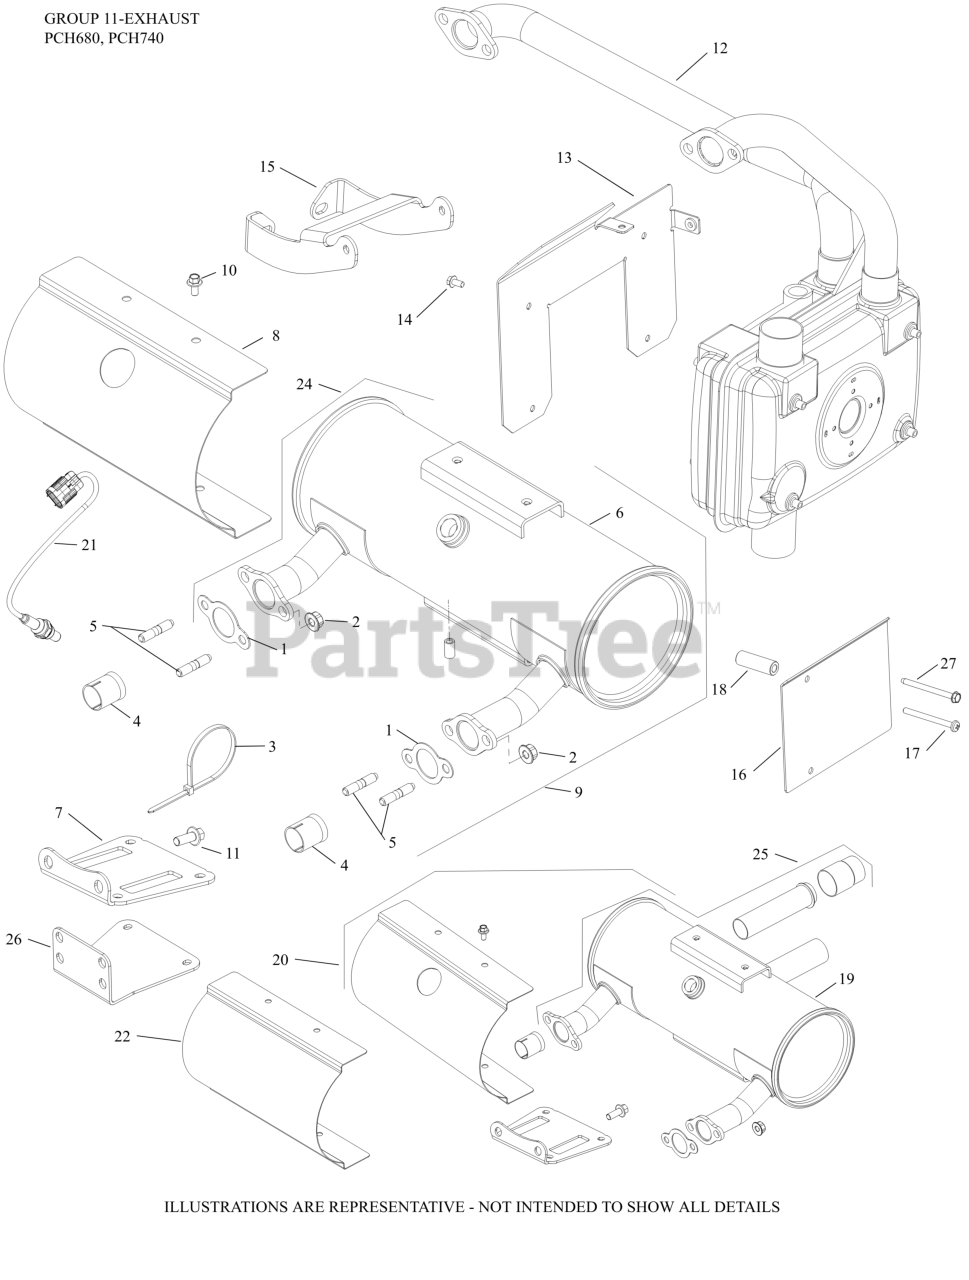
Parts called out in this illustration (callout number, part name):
1	GASKET, EXHAUST
2	NUT, HEX FLANGE LOCK (M8)
4	LINER, EXHAUST PORT
21	SENSOR, OXYGEN (M18 x 1.5 THREADS)
